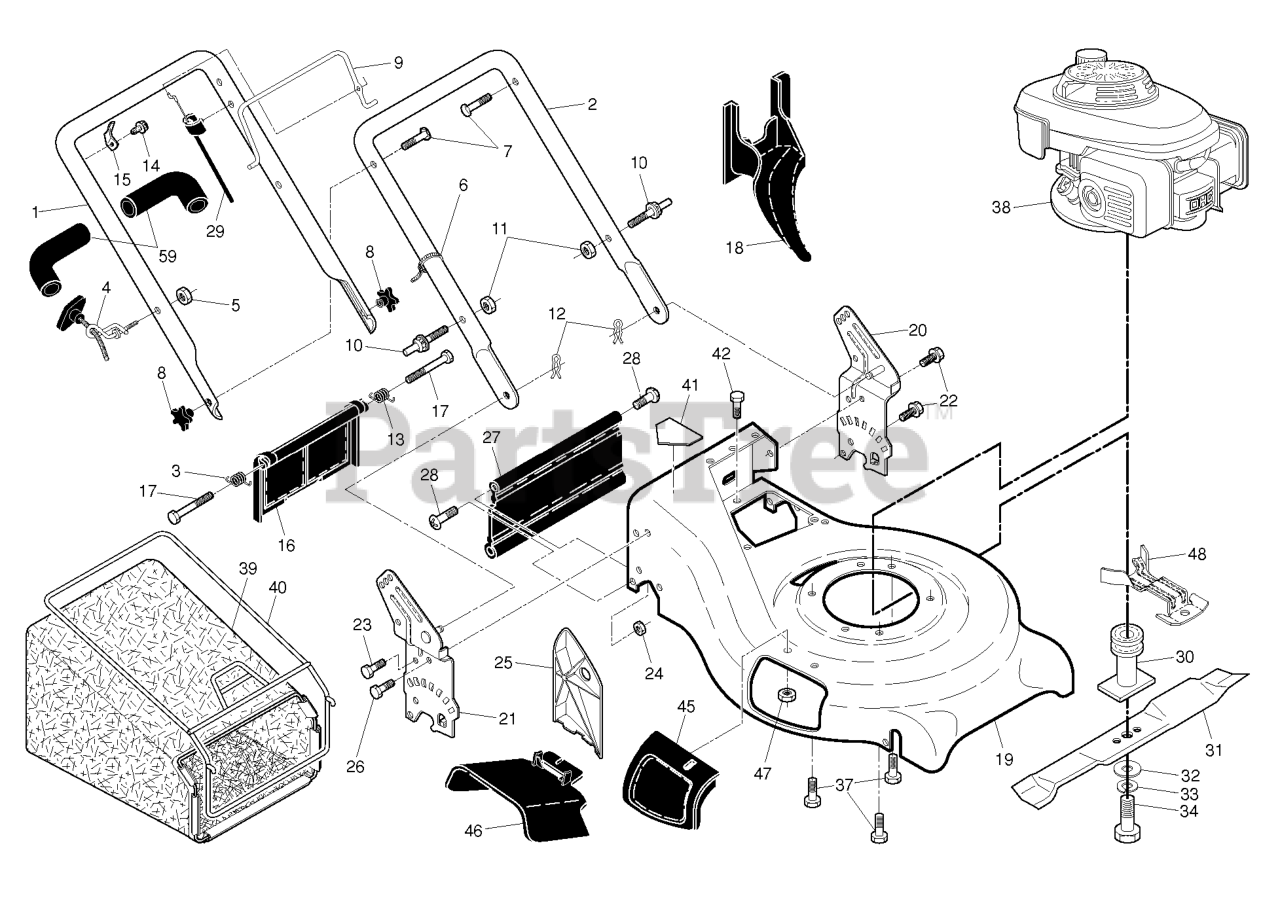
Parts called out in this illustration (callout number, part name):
1	HANDLE.ASM.UPPER.W/GRIP
2	HANDLE.LOWER.21.GREY
3	SPRING.RH.REAR.DOOR.21.RWGD
4	RB GUIDE.ROPE.STD.BLK.ZIN WSL
5	NUT
6	TIE GUIDE
7	BOLT, HANDLE 5/16-18X1.75
8	KNOB.HANDLE.PLASTIC.STAR.BLACK
9	BAIL.CONTROL.MZR.BS.ORANGE
11	NUT.LOCK.5/16-18
12	HAIRPIN COTTER
13	SPRING.LH.REAR.DOOR.21.RWGD
15	BRACKET.UPSTOP.RT
16	REAR DOOR ASSEMBLY
18	PLUG.MULCHER.RGD.21.
19	HOUSING.21.RWD.ORANGE.WALK.
20	BRACKET.HNDL.ASM.21.RWGD.LT.OR
21	BRACKET.HNDL.ASM.21.RWGD.RT.OR
22	BOLT.HEX.HD.WASHER.5/16-18X.75
23	BOLT, HEX HEAD 5/16-18
24	NUT.71038.31-18.HEX.NYLOCK
25	CLIPPING DEFLECTOR
27	SKIRT.REAR.21.RWGD.BLACK(2 2M)
28	HINGE SCREW
29	CABLE.MZR.47.75.SNAP-IN.PU.L
30	ADAPTER.BLADE/PULLEY.25M
31	BLADE.21.PUSH/RWGD/FWGD
32	WASHER,HARDEN
33	LOCKWASHER
34	SCREW, HEX HD 3/8-24 X 1-3/8
37	BOLT 3/8-16X1-1/8
39	RP.GBAG.93230247T.SILV.CROWN.B
40	FRAME.GBAG.21.RWGD.SC
41	DANGER DECAL
42	SCREW 14-20 X 5/8
45	MULCHER DOOR ASM.
46	DEFLECTOR, DISCHARGE
48	BRACKET.ENG/BELTKEEPER.BZP
59	GRIP.HANDLE.FOAM.WIDE.(1 SIDE)
